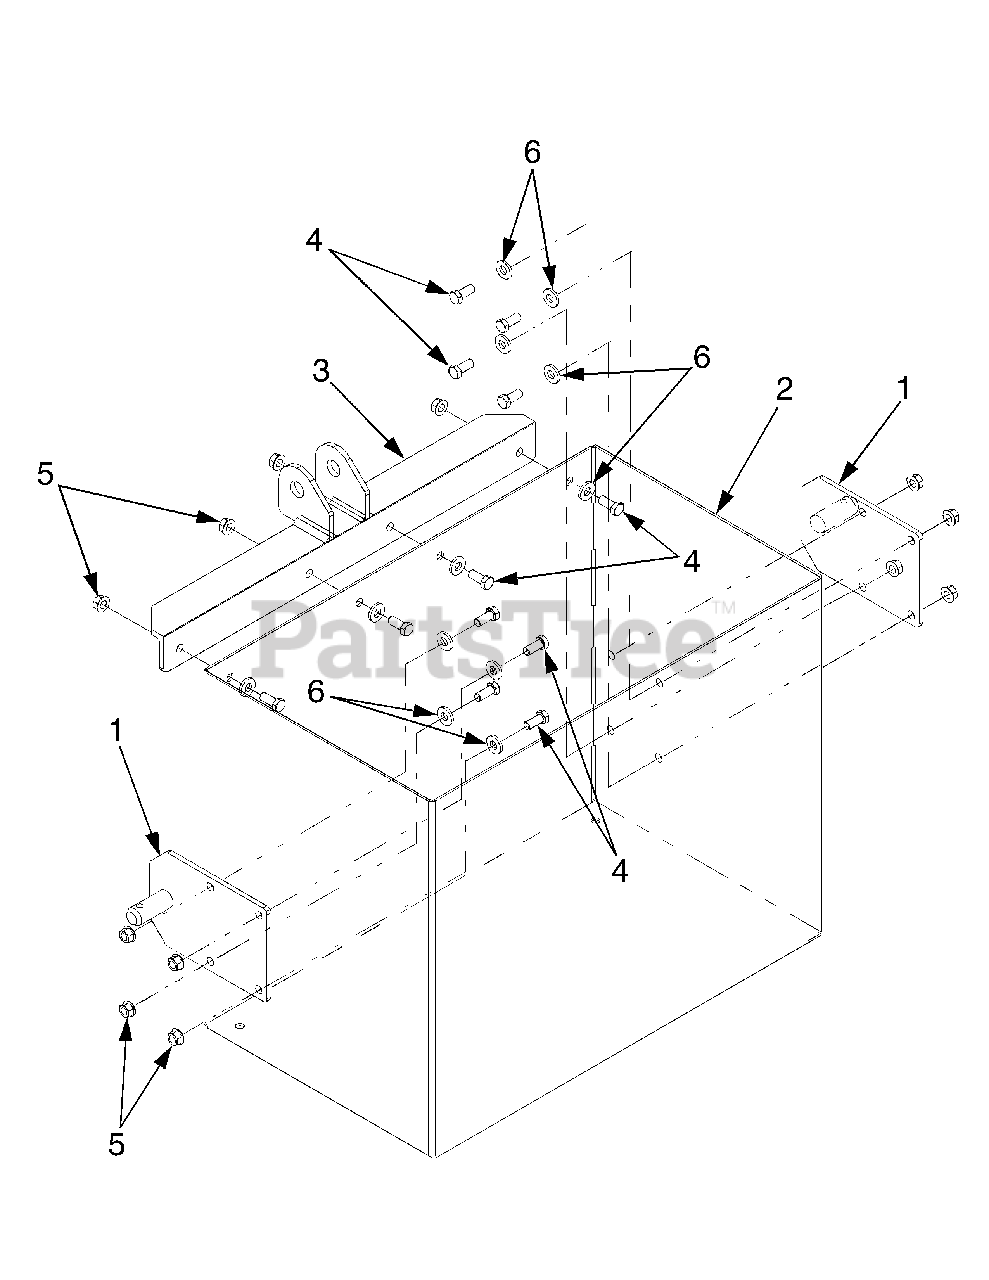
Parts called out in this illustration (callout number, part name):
1	Pin Bracket Ass’y.
2	Box Assembly (5000 Series)
3	Angle Bracket
4	HHC Screw, 3/8-16 x .88 GR5
5	Flange Lock Nut, 3.8-16 GRF
6	Flat Washer, .406 x .875 x .105
